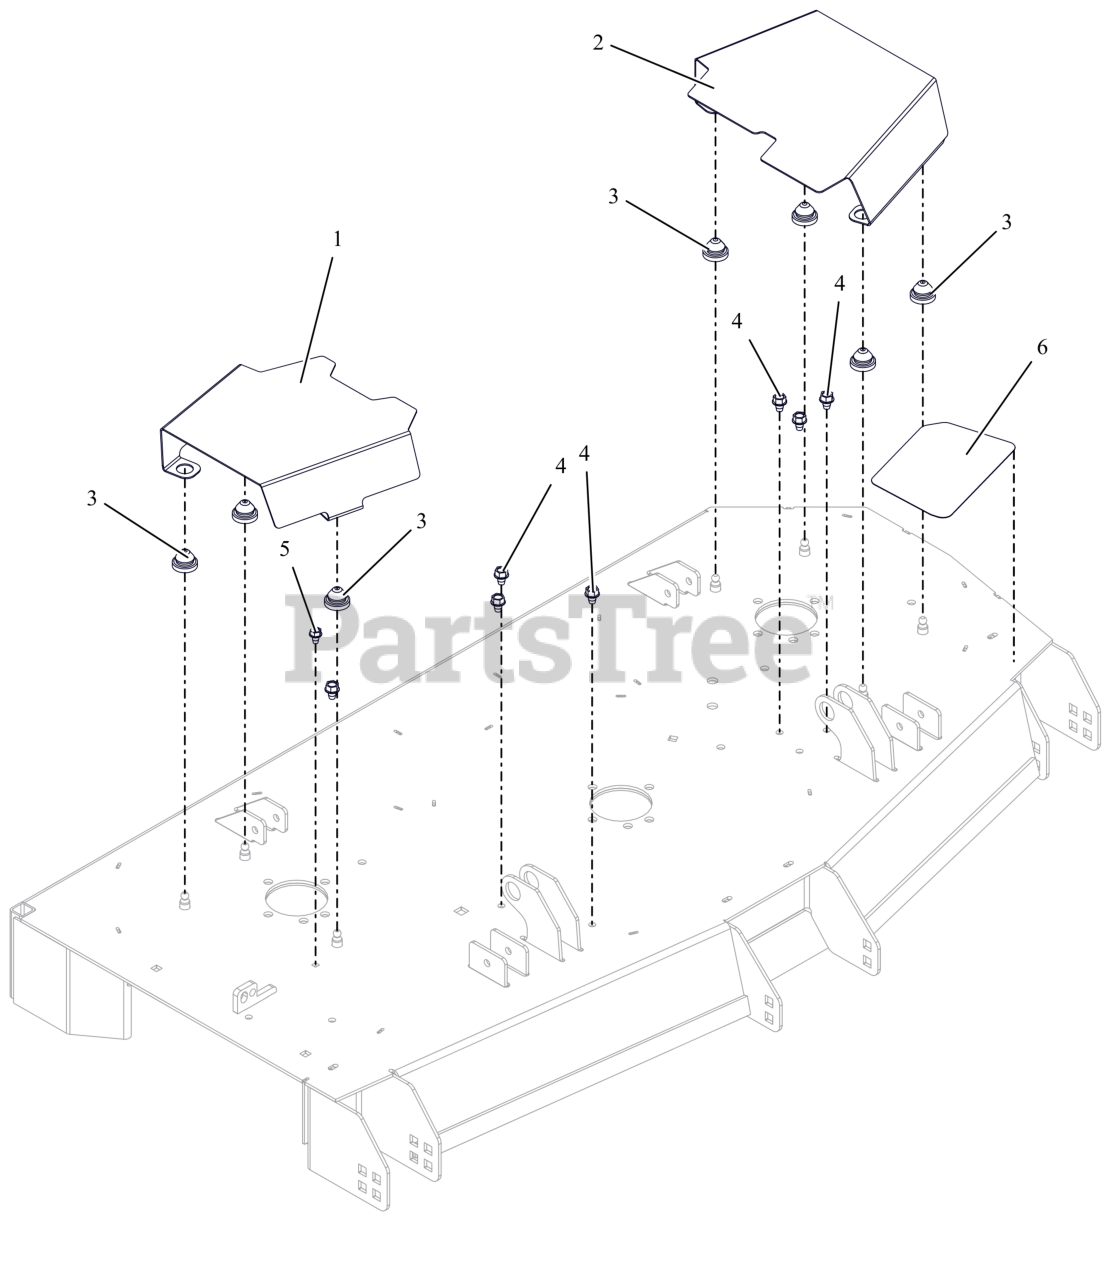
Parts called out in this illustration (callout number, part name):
1	COVER- BELT 52" RIGHT
2	COVER- BELT 52" LEFT
3	COUPLING, RUBBER PUSH-IN
4	SCR,TAP .375-16X.50 HWH TR ZCC
5	SCR,TAP .312-18X.50 HWH TR ZCC
6	GRIP, STEP ANTI SKID HD XF3
